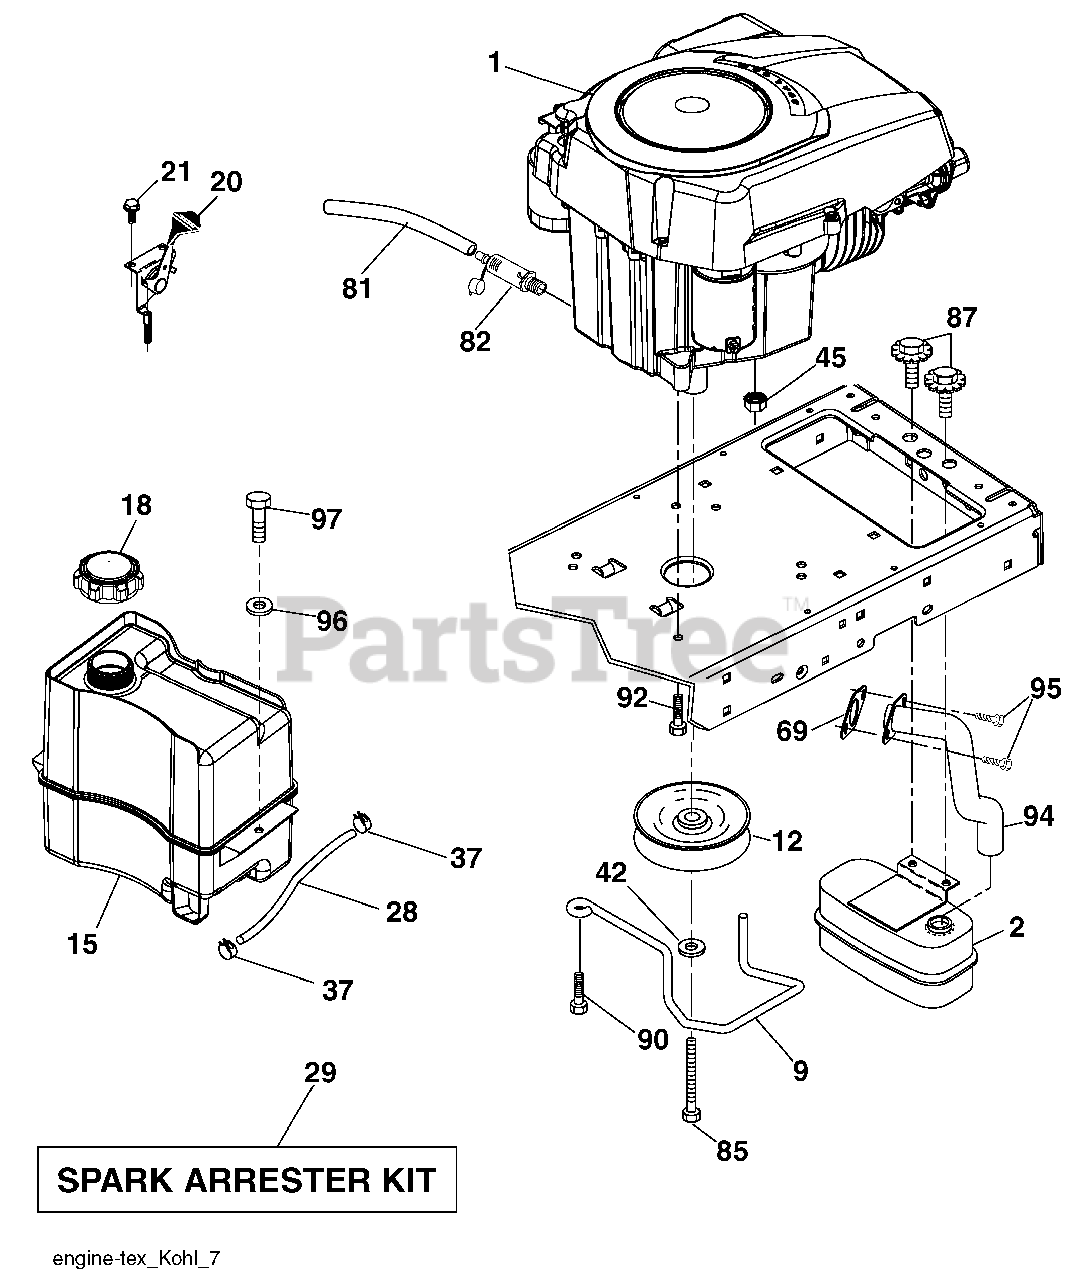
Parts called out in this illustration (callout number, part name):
9	Keeper Belt Engine
12	Pulley Engine
15	Tank Fuel
18	Cap Asm
20	Control Throttle
21	Screw # 10 x 0.750
28	Fuel Line
29	Spark Arrester Kit
37	Clamp Hose
42	Washer Lock 7/16
45	Nut Keps Hex 1/4-20 unc
81	Tube Drain Oil Easy
82	Plug Drain Oil
85	Bolt Hex 7/16-20 x 4 x Gr. 5-1.5 Thr
87	Bolt 5/16-18 unc x 3/4 w/Sems
90	Screw 3/8-16 x 1
92	Screw 3/8-16 x 1
94	Tube Exhaust
95	Screw Socket Hd. 5/16-18 x .75
96	Washer 9/32 x 7/8 x 16 Ga.
97	Screw 1/4-20 x 3/4
